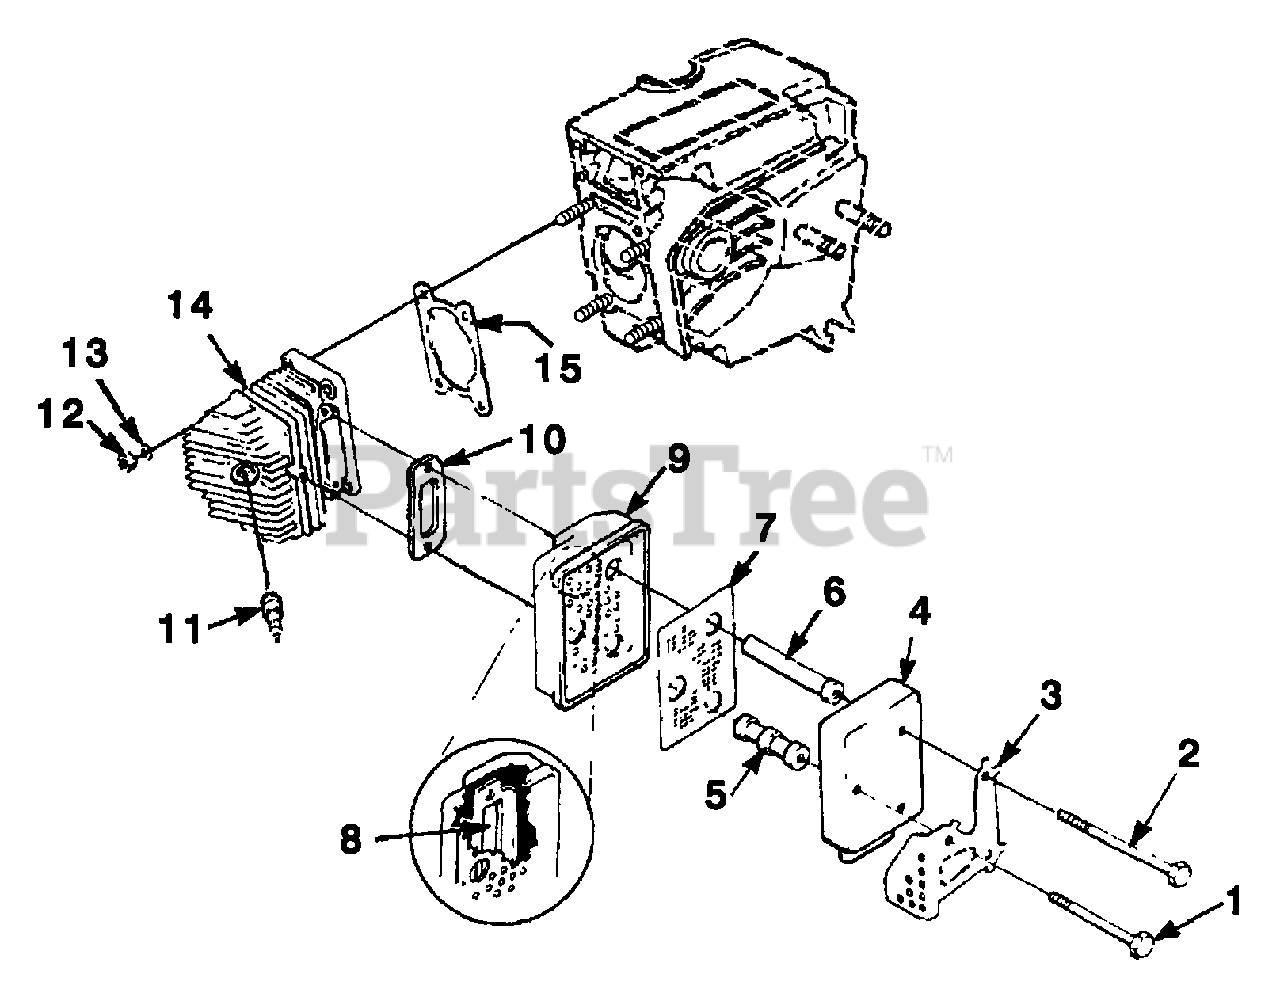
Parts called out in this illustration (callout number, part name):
1	SCREW - Hex Hd
2	SCREW - Hex Hd (1/4-20 X 3")
3	SHIELD - Muffler
4	CAP - Muffler
5	SUPPORT - Short
6	SUPPORT - Long
7	SCREEN - Spark Arrestor
8	PLATE Muffler
9	BODY - Muffler
10	GASKET - Muffler
11	SPARK PLUG
12	NUT - (1/4-28 X 3/8")
13	WASHER - Lock (1/4")
14	CYLINDER
15	GASKET - Cylinder
